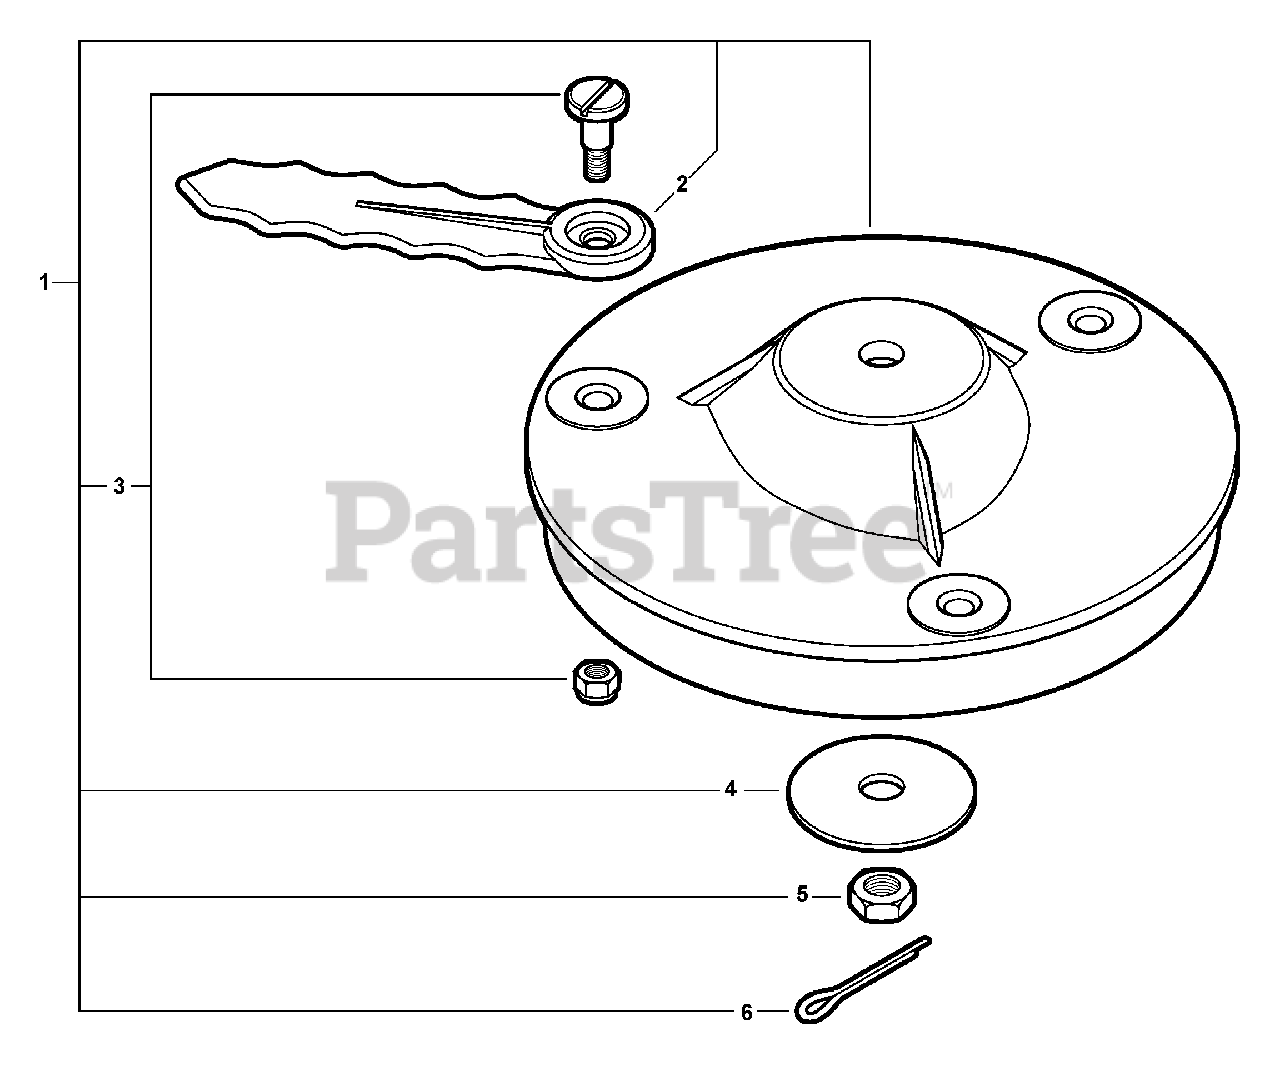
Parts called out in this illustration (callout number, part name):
1	PRO MAXI-CUT HEAD
2	BLADE SET
3	FASTENER SET
4	WASHER, MOUNTING
6	PIN, COTTER 2×22
